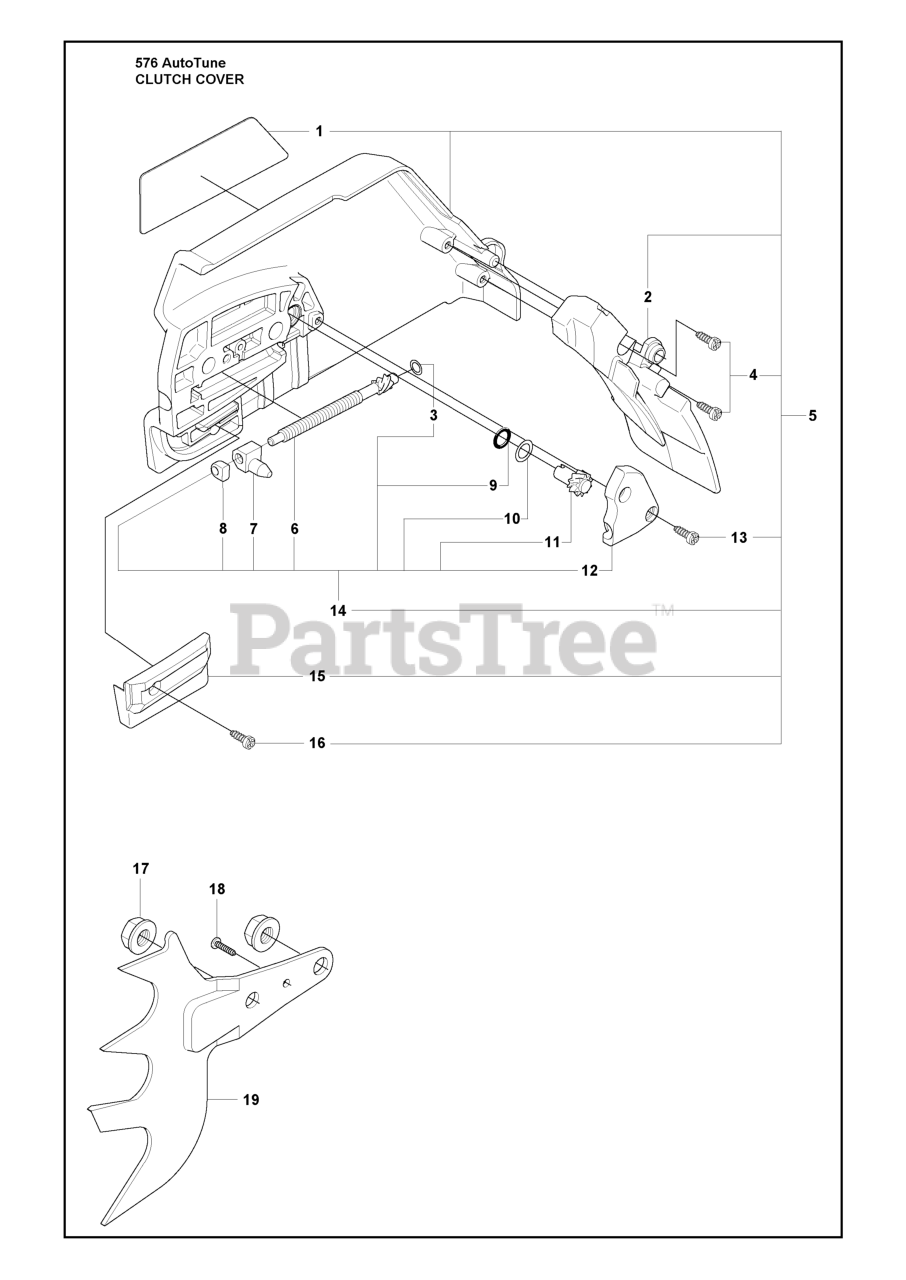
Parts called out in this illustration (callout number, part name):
5	CLUTCH COVER ASSY
6	WORM SCREW / ADJUSTER
11	RP ADJUSTER
14	KIT-CHAIN TENSIONER
15	CHAIN GUIDE
17	NUT M8 FLANGE
19	FELLING DOG
